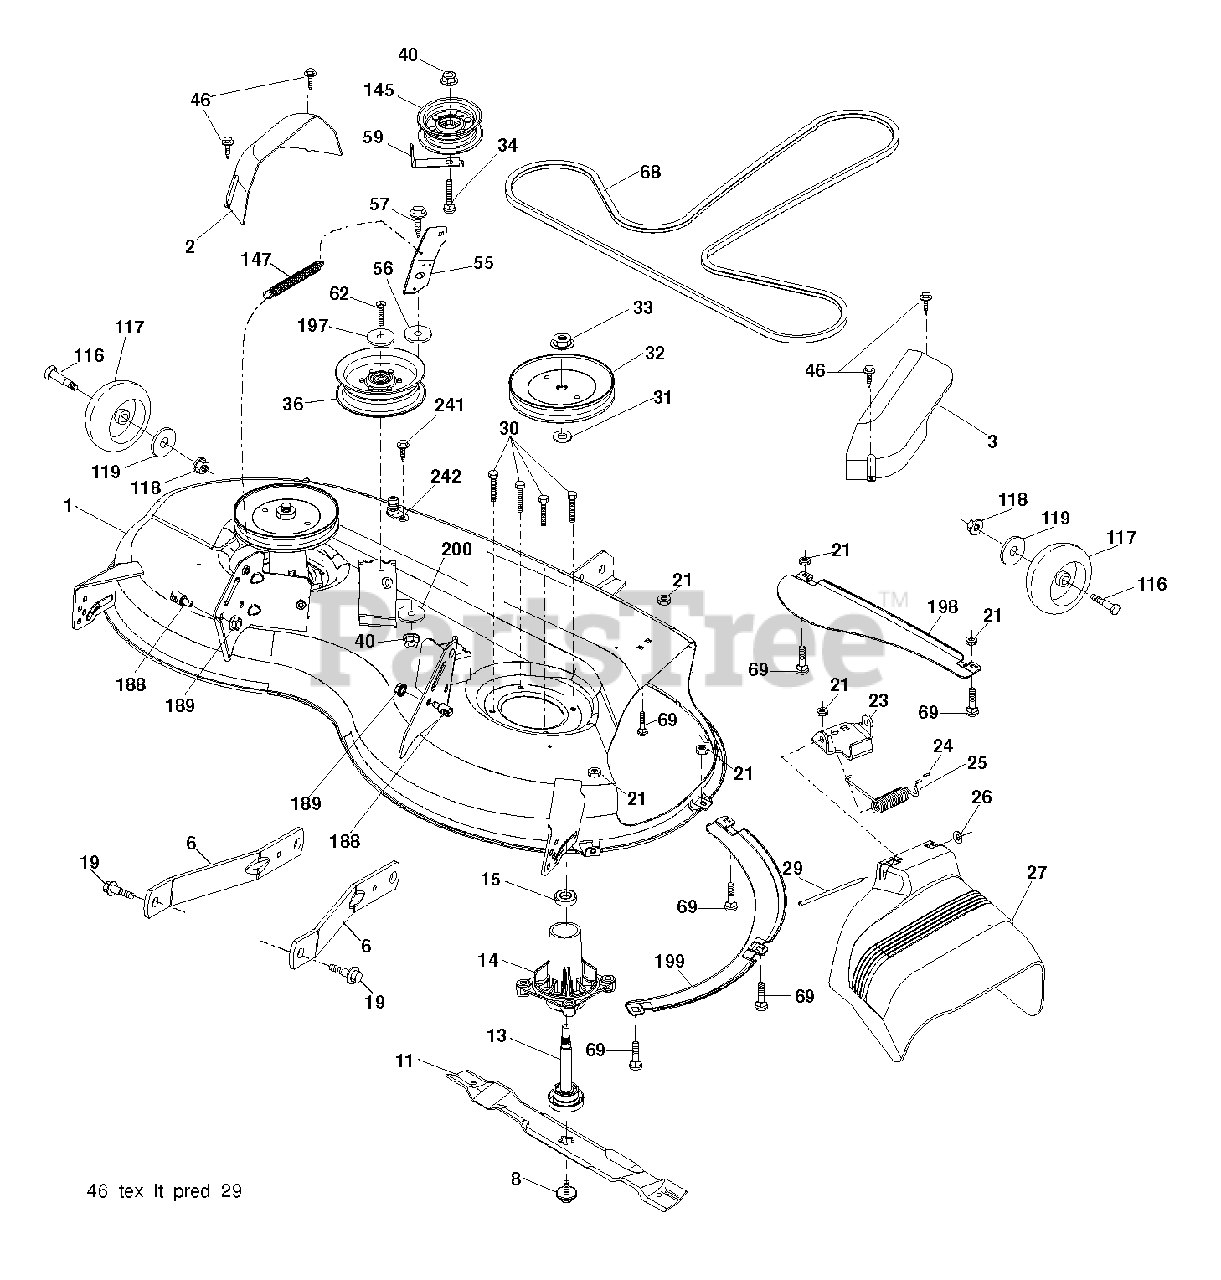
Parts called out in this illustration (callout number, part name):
1	DECK.WELDMENT.46"
2	COVER.MANDREL.LH.46"
3	COVER MANDREL RH
6	ARM.SUSPENSION.MOWER.R
8	BOLT.WASHER.ASM.7/16-2
11	BLADE 46" HI LIFT
13	SHAFT.ASM.MDRL.N/GREASE.38
14	HOUSING MANDREL
19	BOLT.SHOULDER
21	LOCKNUT
23	BRKT.DEFLECTOR.38"2005+
24	CAP-SLEEVE LT
25	SPRING.TORSION.DEFLECT
27	SHIELD.DEFLECTOR.MOWER.46"BLAC
29	ROD.HINGE
30	SCREW, WASHER HEAD
31	WASHER.SPACER.MANDREL
32	PULLEY.MANDREL.5.438.PD
33	NUT.FLANGE.LOCK.TOP
34	BOLT.3/8-16X1.50
36	PULLEY.IDLER.2006
40	NUT LOCK FLG 3/8-16 UNC
46	SCREW.1/4-20X5/8
56	SPACER.RETAINER
57	SCREW 3/8-16X1
62	BOLT-HEX EAK
68	V BELT
69	BOLT
116	Shield Bolt, A 2.41 B 1.66
117	WHEEL.GAGE.HALF.SPOKED
118	LOCKNUT
119	WASHER
145	PULLEY.IDLER.48"PRIMARY
147	SPRING.MOWER.DRIVE.ELECTRIC
188	STUD.FASTNER.W/ANTI-ROTATE
189	NUT LOCK HEX FLANGE 5/16-18
197	WASHER
198	BAFFLE CENTER FRONT
199	BAFFLE FRONT RH
200	WASHER.13/32 X 1 X 1/2.11GUARD
